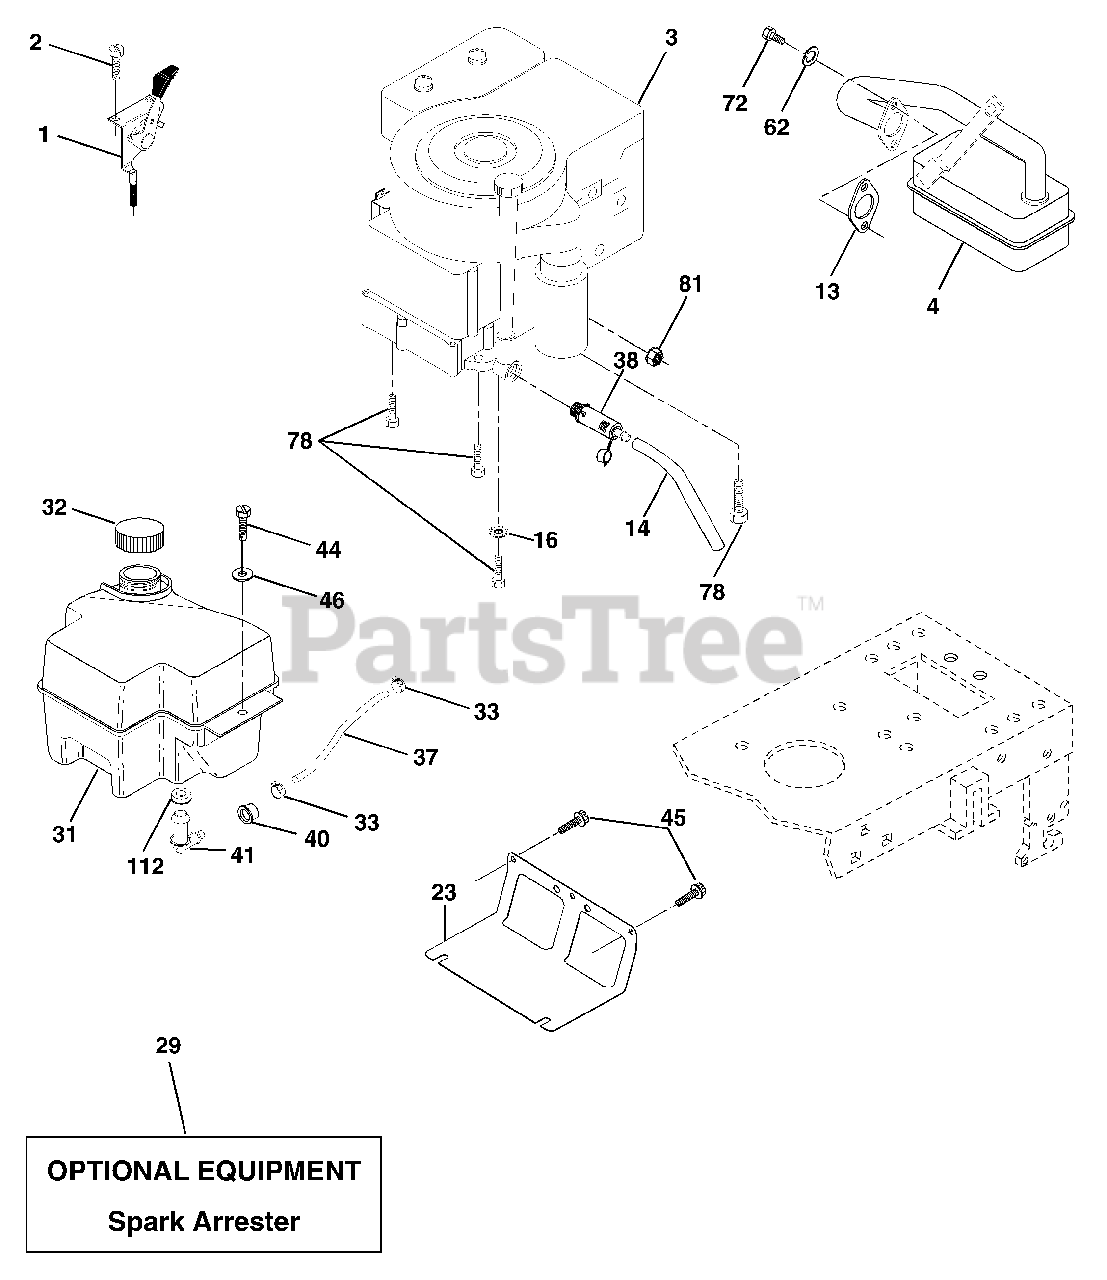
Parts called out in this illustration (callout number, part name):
1	Control Th/ch Flag
2	Screw Hex Thd Cut 1/4-20 x 1/2
4	Muffler
13	Gasket Eng
14	Tube Drain Oil Easy
16	Washer Lock Ext Tooth 3/8
23	Shield Brn/Dbr Guard
29	Kit Spark Arrestor (Flat Scrn)
31	Tank Fuel Front
32	Cap Asm Fuel W/sym Vented
33	Clamp Hose Black
37	Line Fuel 20"
38	Plug Drain Oil Easy
40	Bushing Snap Nyl Blk Fuel Line
41	Stem Tank Fuel
44	Screw Hexwsh Thdrol 1/4-20x3/4
45	Screw Hexwsh Thdr 3/8-16 x 3/4
46	Washer 9/32 X 7/8 X 16 Ga
62	Washer Lock Hvy Hlcl Spr 5/16
72	Screw Hex Hd Cap 5/16-18 x 3/4
78	Screw 3/8-16x1-1/4
81	Nut Keps Hex 1/4-20 UNC
112	Bushing
